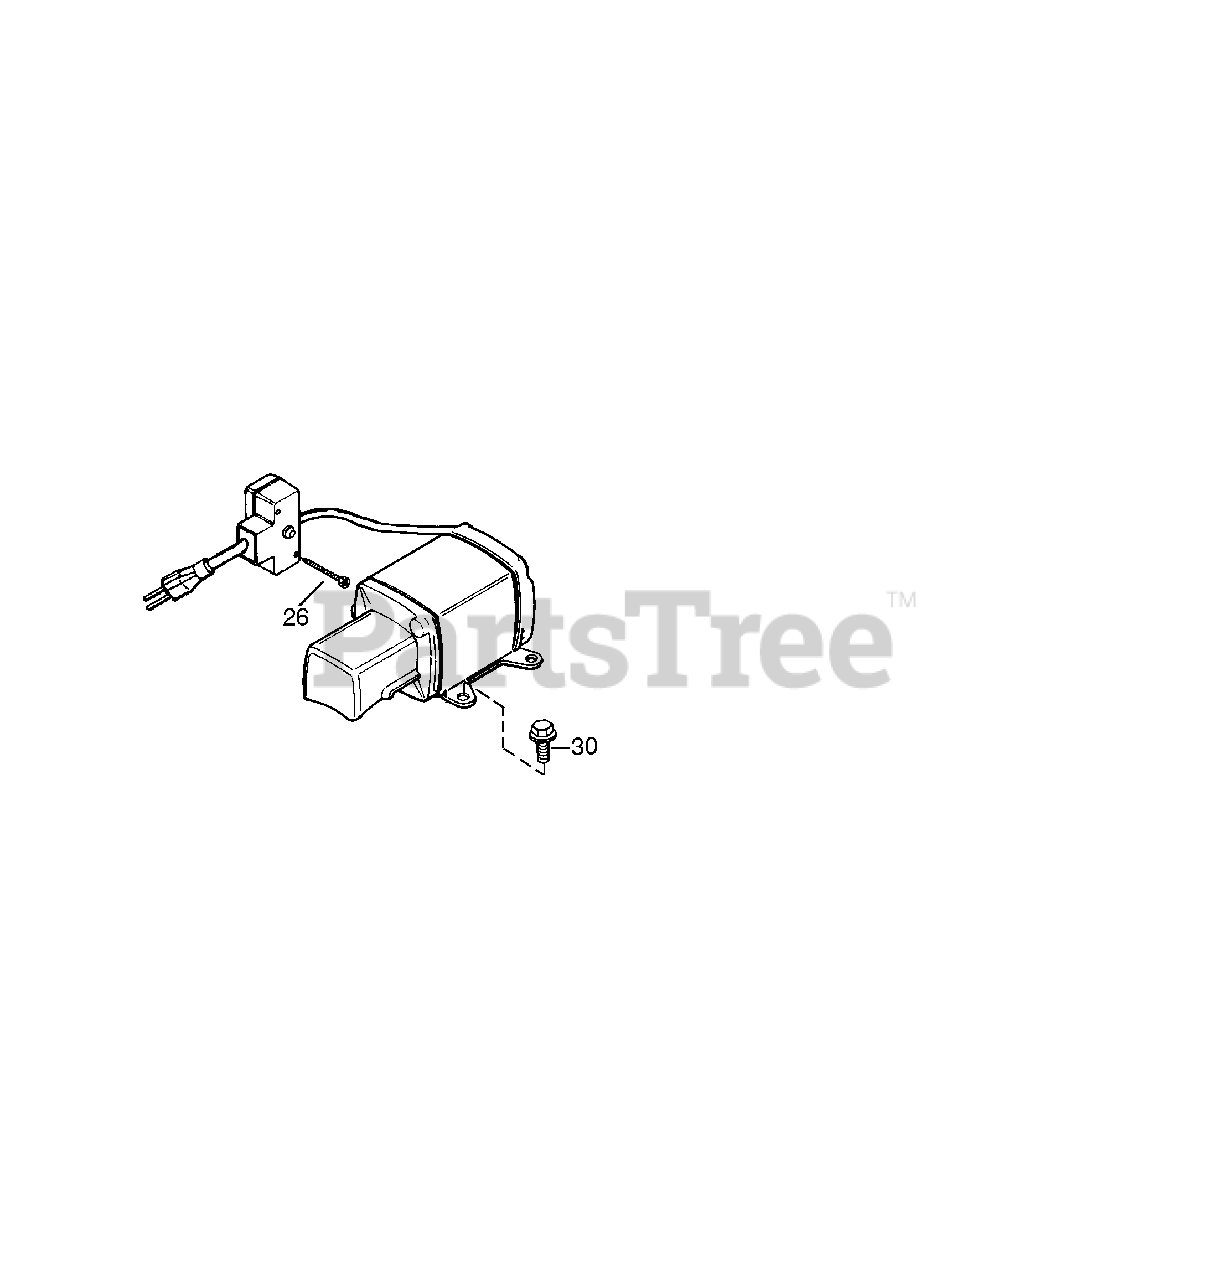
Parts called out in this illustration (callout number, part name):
26	Screw, 6-32 x 2-1/2"
26	Screw, 12-16 x 5/8"
30	Screw, Torx T-30, 1/4-20 x 23/32"
